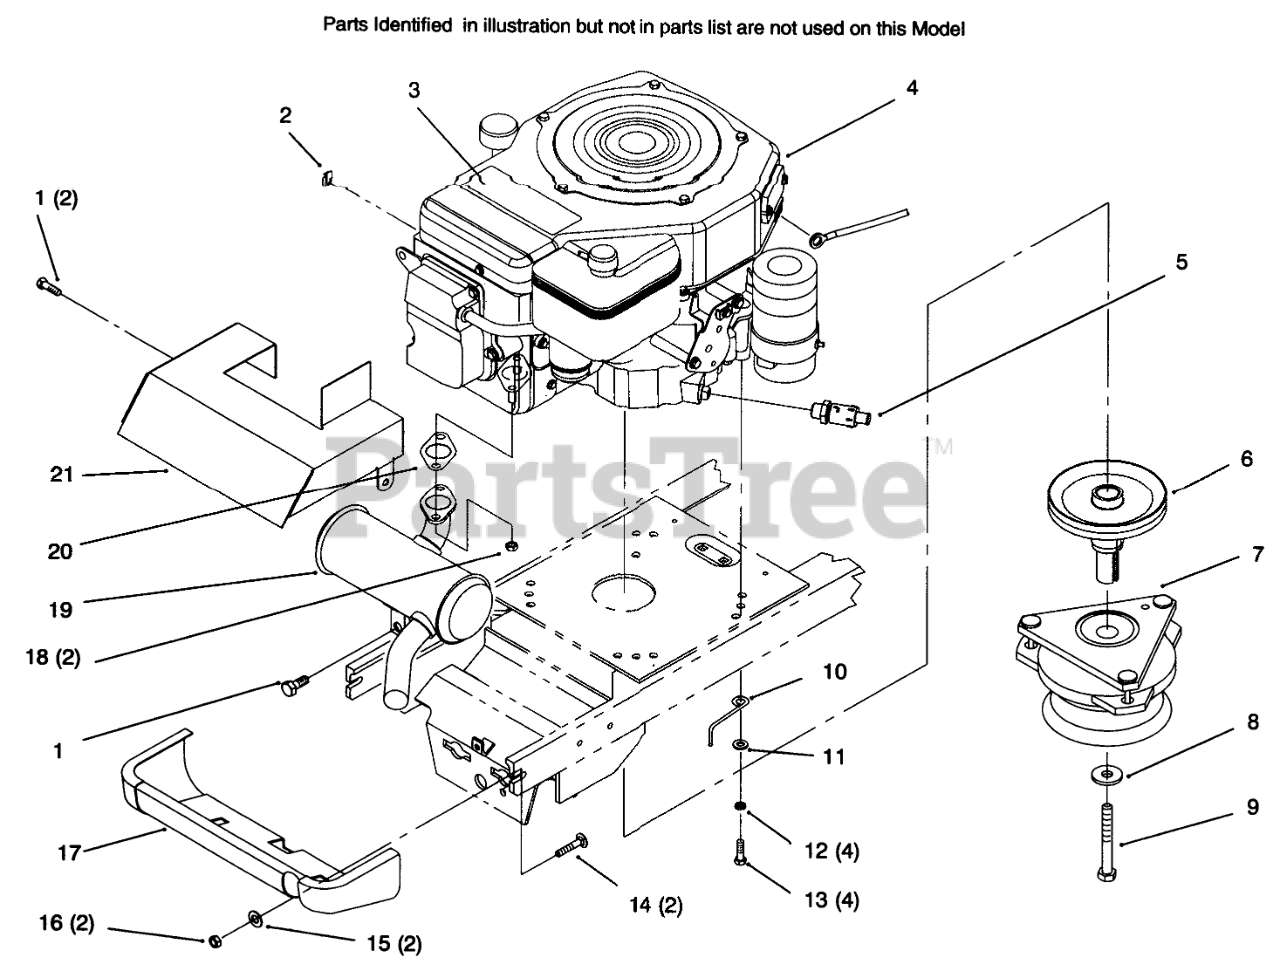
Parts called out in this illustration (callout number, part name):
1	SCREW
2	CLIP-RETAINER, WIRE
3	DECAL - LOGO
4	Engine-Kohler
5	VALVE-DRAIN, OIL
6	PULLEY- ENGINE GEAR
7	CLUTCH - PTO
8	WASHER
9	HHCS-M10X1.5X110 ESL
10	GUIDE-BELT
11	WASHER-PLAIN
12	WASHER-LOCK
13	SCREW-CAP, HH
14	BOLT-CARR
15	WASHER-FLAT
16	NUT-LOCK, NI
17	Shield-Muffler
18	NUT-HF
19	Muffler
20	Gasket-Exhaust
21	SHIELD-MUFFLER
